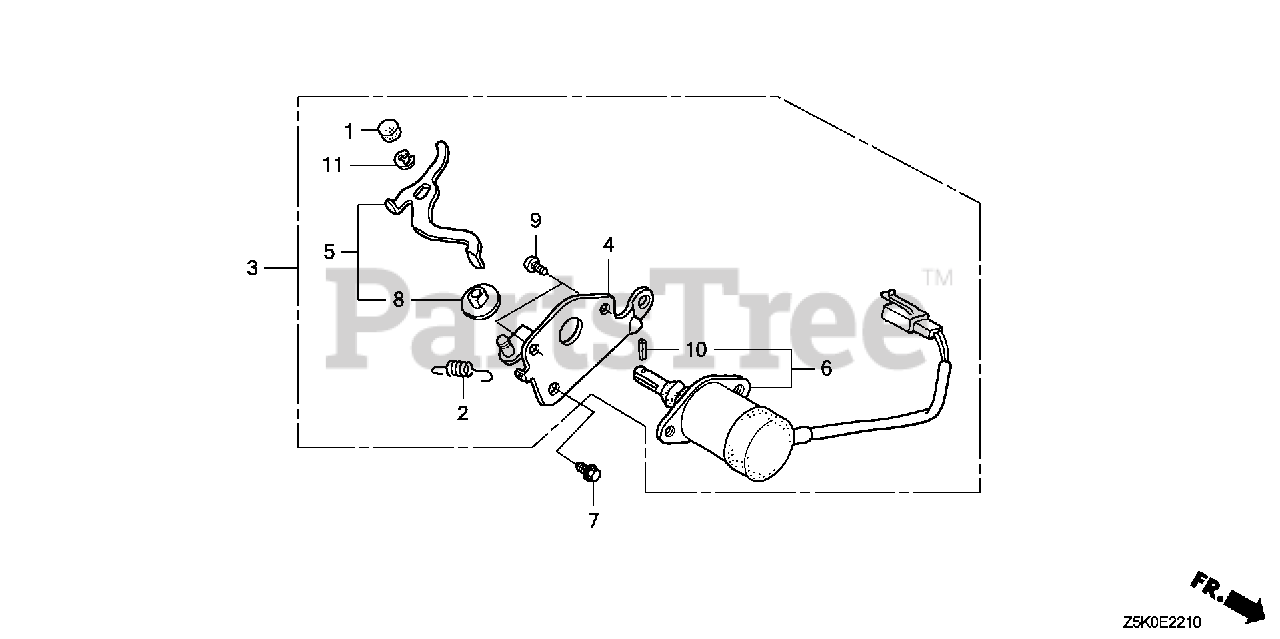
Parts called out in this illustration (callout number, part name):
1	CAP, CHOKE LEVER
2	SPRING, CHOKE RETURN
3	AUTO-THROTTLE ASSY.
4	STAY, SOLENOID THROTTLE
5	LEVER, SOLENOID THROTTLE
6	SOLENOID ASSY.
7	BOLT, FLANGE (6X12) (CT200)
8	BUSH, AUTO-THROTTLE LEVER
9	SCREW, PAN (5X8)
10	PIN, SPRING (2X6)
11	E-RING (4MM)
